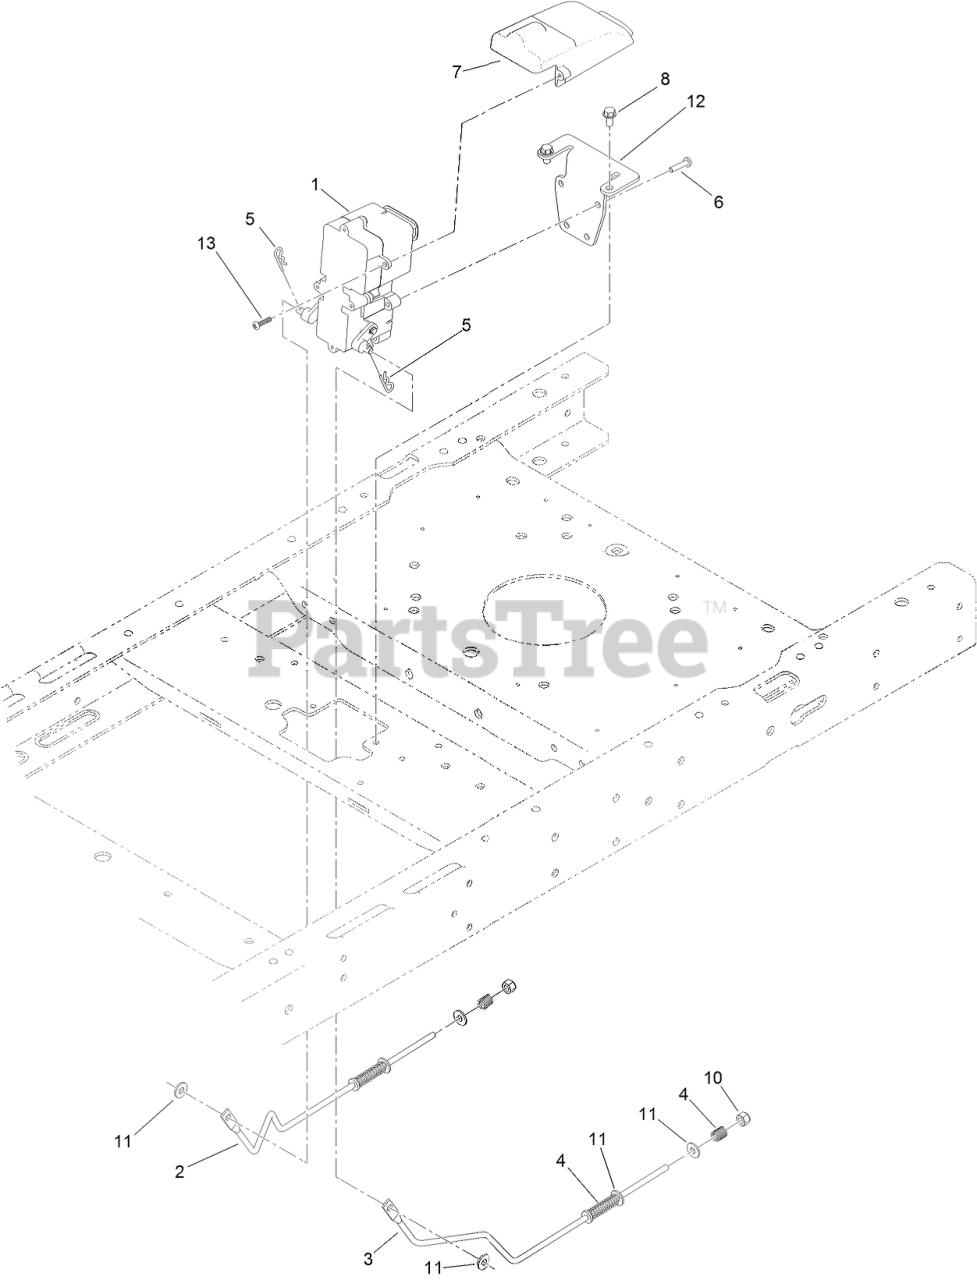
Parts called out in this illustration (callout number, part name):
1	BRAKE BOX ASM
2	ROD-BRAKE, RH
3	ROD-BRAKE, LH
4	SPRING-COMPRESSION
5	PIN-COTTER
6	SCREW-PPH
7	COVER-CONNECTOR
8	SCREW-HWH
10	NUT-LOCK, NI
11	WASHER
12	BRACKET-MOUNT, BRAKE
13	SCREW-PPH
